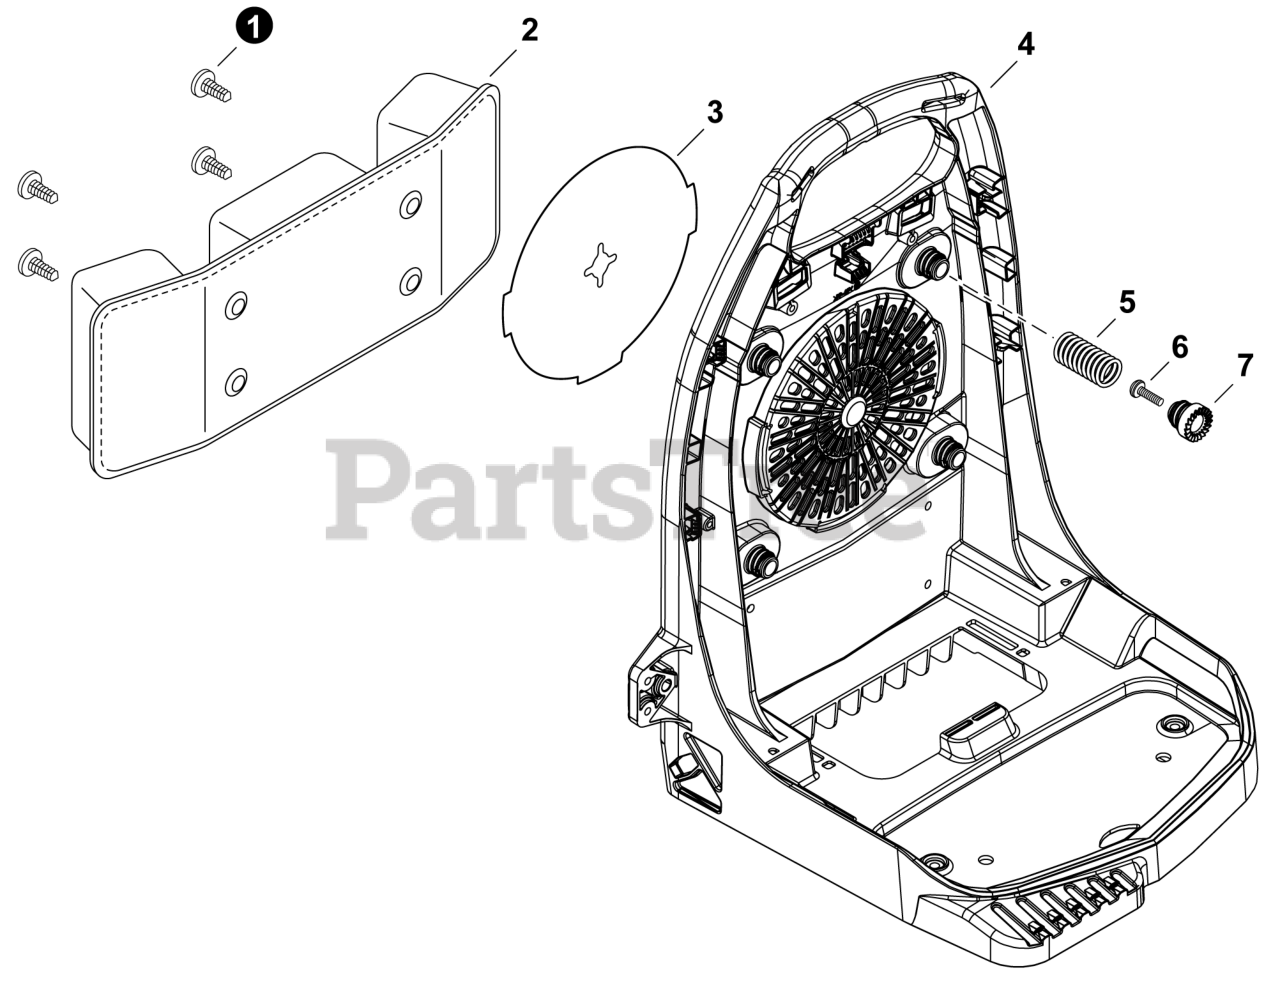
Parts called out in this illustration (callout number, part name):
2	PAD, WAIST
3	INSERT, COLD WEATHER
4	FRAME, BACKPACK
5	SPRING, COMPRESSION
6	BOLT, TORX 5x20
7	HOLDER, SPRING
